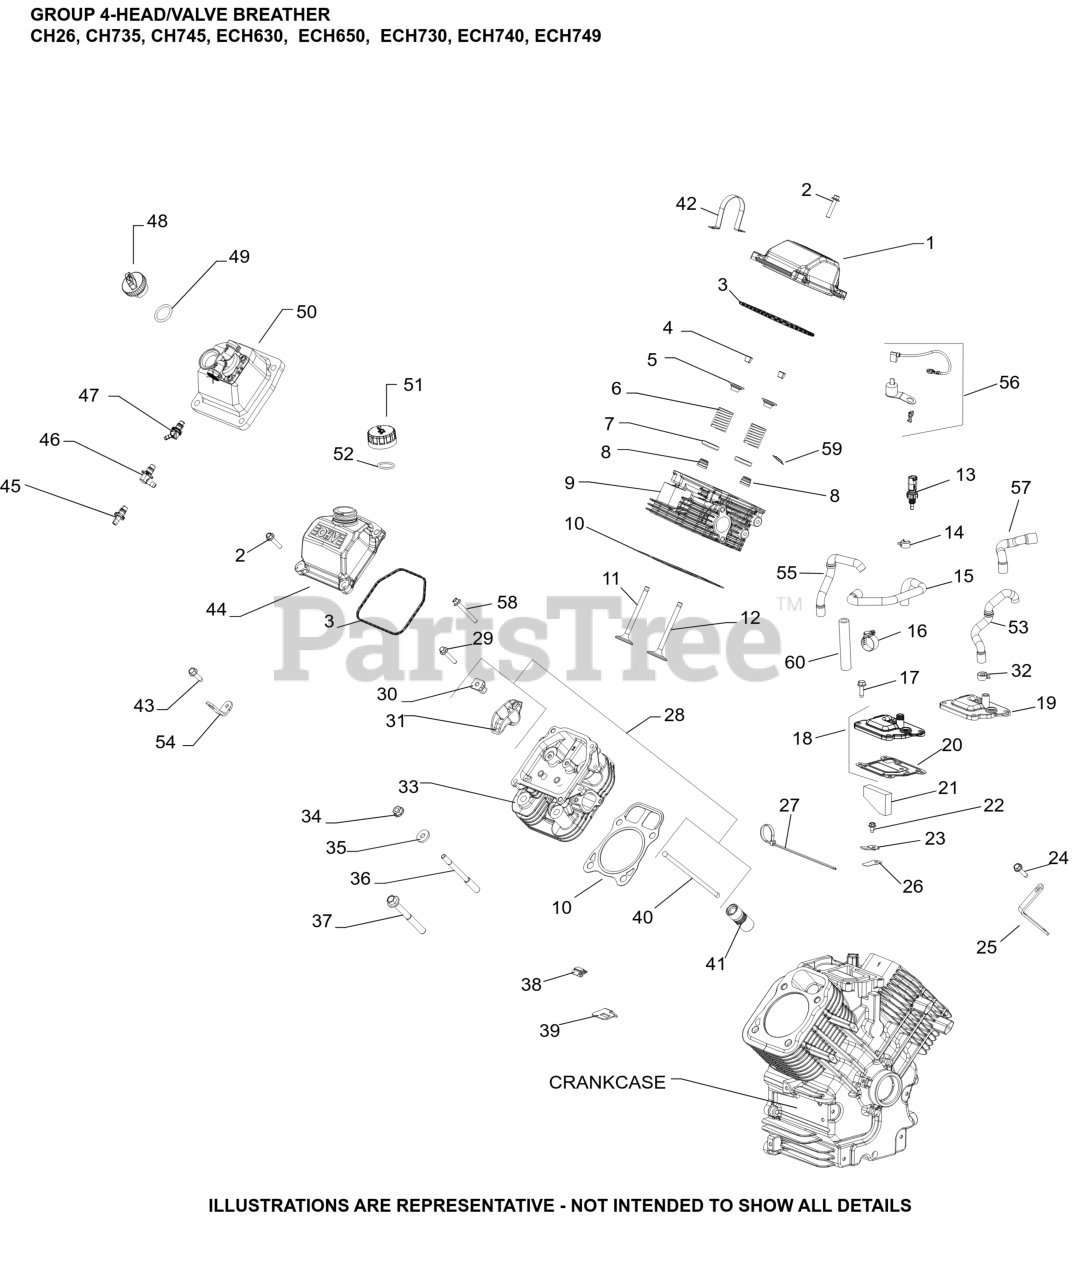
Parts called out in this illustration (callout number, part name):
1	KIT, VALVE COVER-PLAIN (PLASTIC)
2	SCREW, FLG M6X1.0X30
3	O-RING (YELLOW), VALVE CO
4	KIT, RETAINER
5	CAP, VALVE SPRING
6	SPRING, VALVE
7	RETAINER, SPRING
8	SEAL, VALVE BAND
9	KIT, CYLINDER HEAD (#1)-(#2481803S)
10	KIT, GASKET CYLINDER HEAD
11	VALVE, EXHAUST
11	VALVE, EXHAUST (.25)
12	VALVE, INTAKE (STD)
12	VALVE, INTAKE (.25)
13	SENSOR, TEMPERATURE
15	HOSE, BREATHER (EFI H/S, HDAC)
17	SCREW, THREAD FORMING
19	COVER, BREATHER
20	GASKET, BREATHER
21	FILTER, BREATHER
22	SCREW, FLG THD FRM M5X.8X10
23	RETAINER, REED
25	STRAP, LIFT
26	REED, BREATHER
28	KIT, VALVE TRAIN
30	PIVOT, ROCKER ARM
31	ARM, ROCKER
32	SPRING CLAMP, HOSE
33	KIT, CYLINDER HEAD (#2)-(#2481804S)
34	NUT, FLG M8X1.25
35	WASHER, FLAT 8.6 MM
36	STUD, M8X1.25
38	CLIP, O2 SENSOR
39	BRACKET, OXYGEN SENSOR
40	ROD, PUSH
41	LIFTER, VALVE HYDRAULIC-USE 25 351 11-S
45	KIT, STRAIGHT FITTING
46	KIT, 90 DEG. FITTING
48	CAP ASSY, OIL FILL (YELLOW)
50	KIT,VALVE COVER-FUEL PUMP
54	STRAP, LIFTING
58	SCREW,HEX FLANGE - USE 25 086 777-S
59	RETAINER, VALVE GUIDE (KM)
